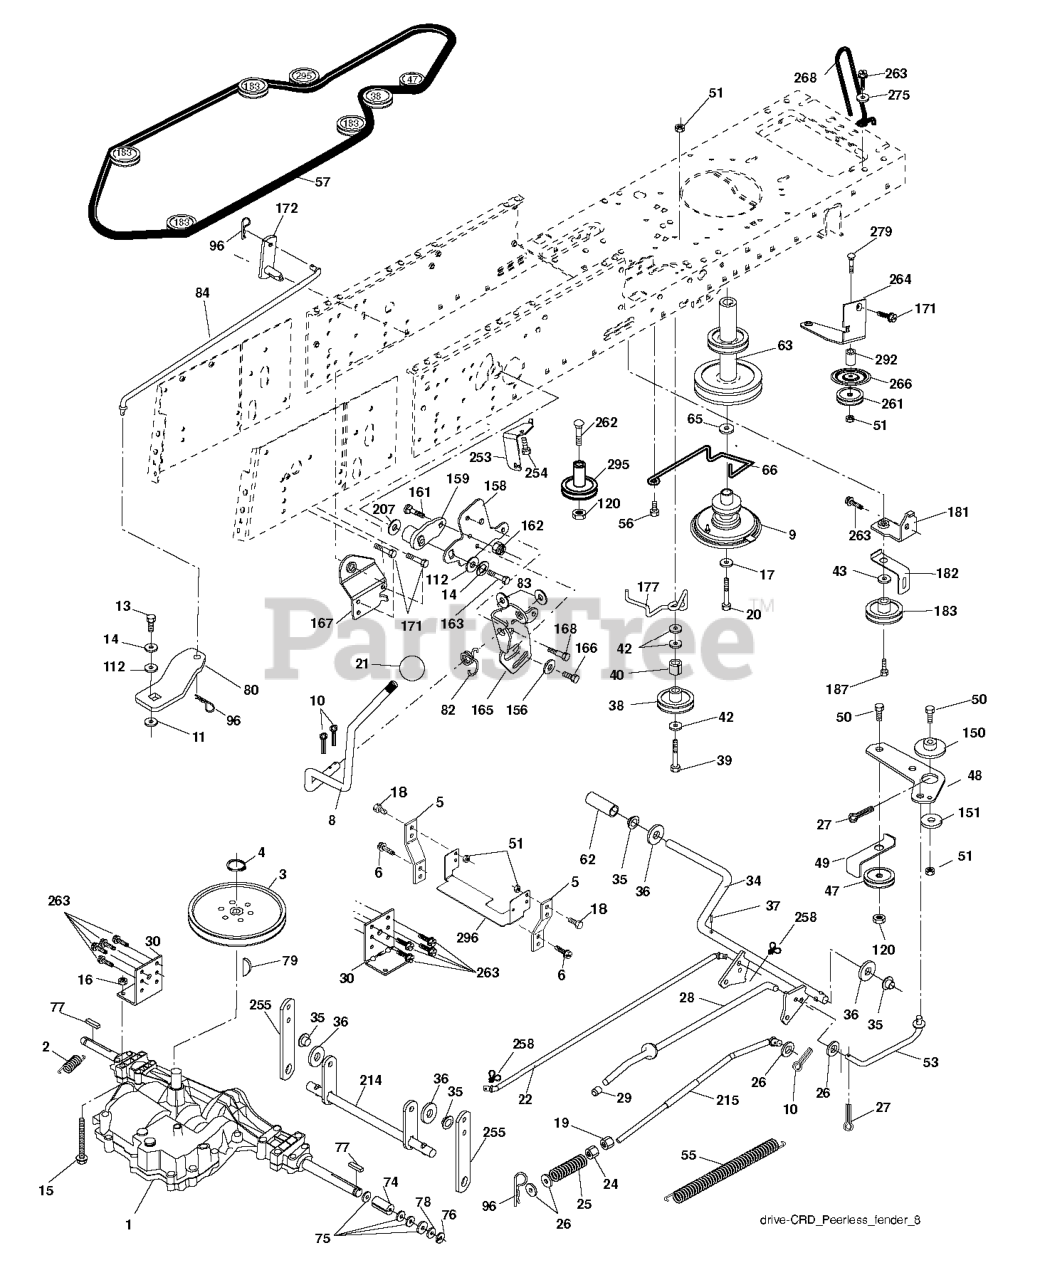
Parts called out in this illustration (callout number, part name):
2	SPRING,BRAKE RETURN
3	PULLEY
4	RETAINING RING LT
5	STRAP TORQUE
6	SCREW 5/16"
8	ROD SHIFT FENDER ADJUST LT
9	CLUTCH.ELECTRIC.OGURA.EURO.
10	PIN COTTER
11	WASH-SHFT PLT LT
13	BOLT 1/4-28X3/4
14	LOCKWASHER
15	BOLT HEX 5/16-18 GR 5
16	NUT.71038.31-18.HEX.NYLOCK
19	NUT
20	BOLT HEX 7/16-20X4-1/4"
21	KNOB.DUCKHEAD.1/2
22	ROD
24	NUT
25	SPRING ROD LT
26	WASHER
27	COTTER PIN
28	ROD, PARKING BRAKE
29	CAP
30	BRKT, MOUNT TRNSAXLE
34	SHAFT, FOOT PEDAL
35	BEARING.NYLON
37	DRIVE PIN
38	PULLEY.FLAT
42	WASHER
47	IDLER PULLEY
48	BELLCRANK, CLUTCH
49	RETAIN BELT
50	BOLT.3/8-16X1.50
53	LINK.CLUTCH.7.66.2005
55	SPRING, RETURN LT
56	SCREW.3/8-16
57	V-BELT.KEV.111"
62	PEDAL COVER T
63	PULLEY.ENGINE.CVX.LT
65	LOCKWASHER
66	KEEPER BELT ENGINE
74	SPACER AXLE
77	SQUARE KEY
79	KEY STD (1373) DANA
82	SHIFT SPRING
83	WASHER
96	RETAINER M
120	NUT LOCK FLG 3/8-16 UNC
150	BUSHING.BELLCRANK.GRD.DR
151	WASHER 12/32X2X10GA
156	WASHER.SRRTD.5/16
158	BRACKET
159	RB HUB.SHIFT
161	BOLT
162	NUT.CROWNLOCK.1/4
165	RP BRACKET
166	CAPSCREW.HXHD.FLG.5/16-18X.625
167	BRACKET.SUPT.SHIFT.CRD
168	BOLT.SHOULDER.5/16-18X
172	SHAFT
181	BRACKET
182	BELT GUIDE
183	PULLEY.V-IDLER.GRND.DR
187	BOLT.5/16-18X1.25
207	WASHER NYL
214	LEVER
253	BRACKET, ANTI-ROTATION
254	SCREW 3/8-16X1
255	SHAFT
258	CLIP RETAINER
261	FLAT IDLER PULLEY
263	SCREW, 3/8-16X3/4
266	PROTECTOR
268	GUARD MUFFLER
275	WASHER
292	SPACER
295	PULLEY IDLER COMPOSITE
